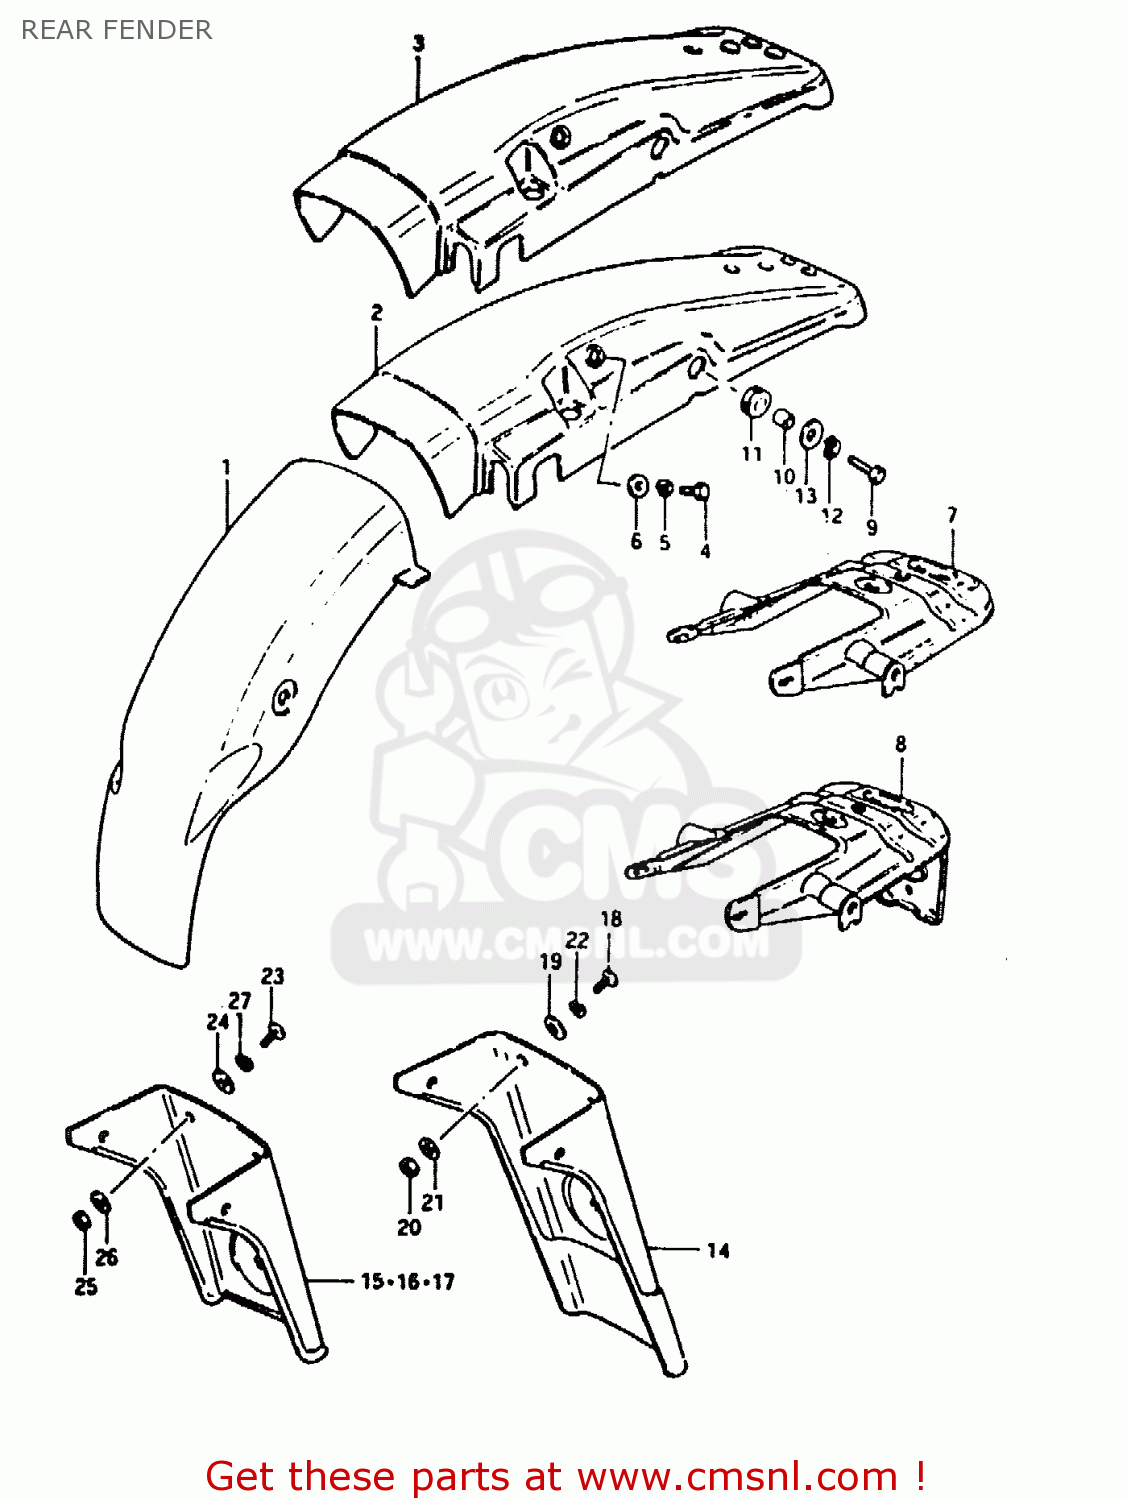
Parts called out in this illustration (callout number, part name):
1	BODY,RR FENDER FR
2	BODY, REAR FENDER REAR
4	BOLT, UPPER
5	LOCK WASHER
6	WASHER
7	REINFORCEMENT
9	BOLT 8X55
10	SPACER (8.2X12X7.5)
11	CUSHION
12	LOCK WASHER
